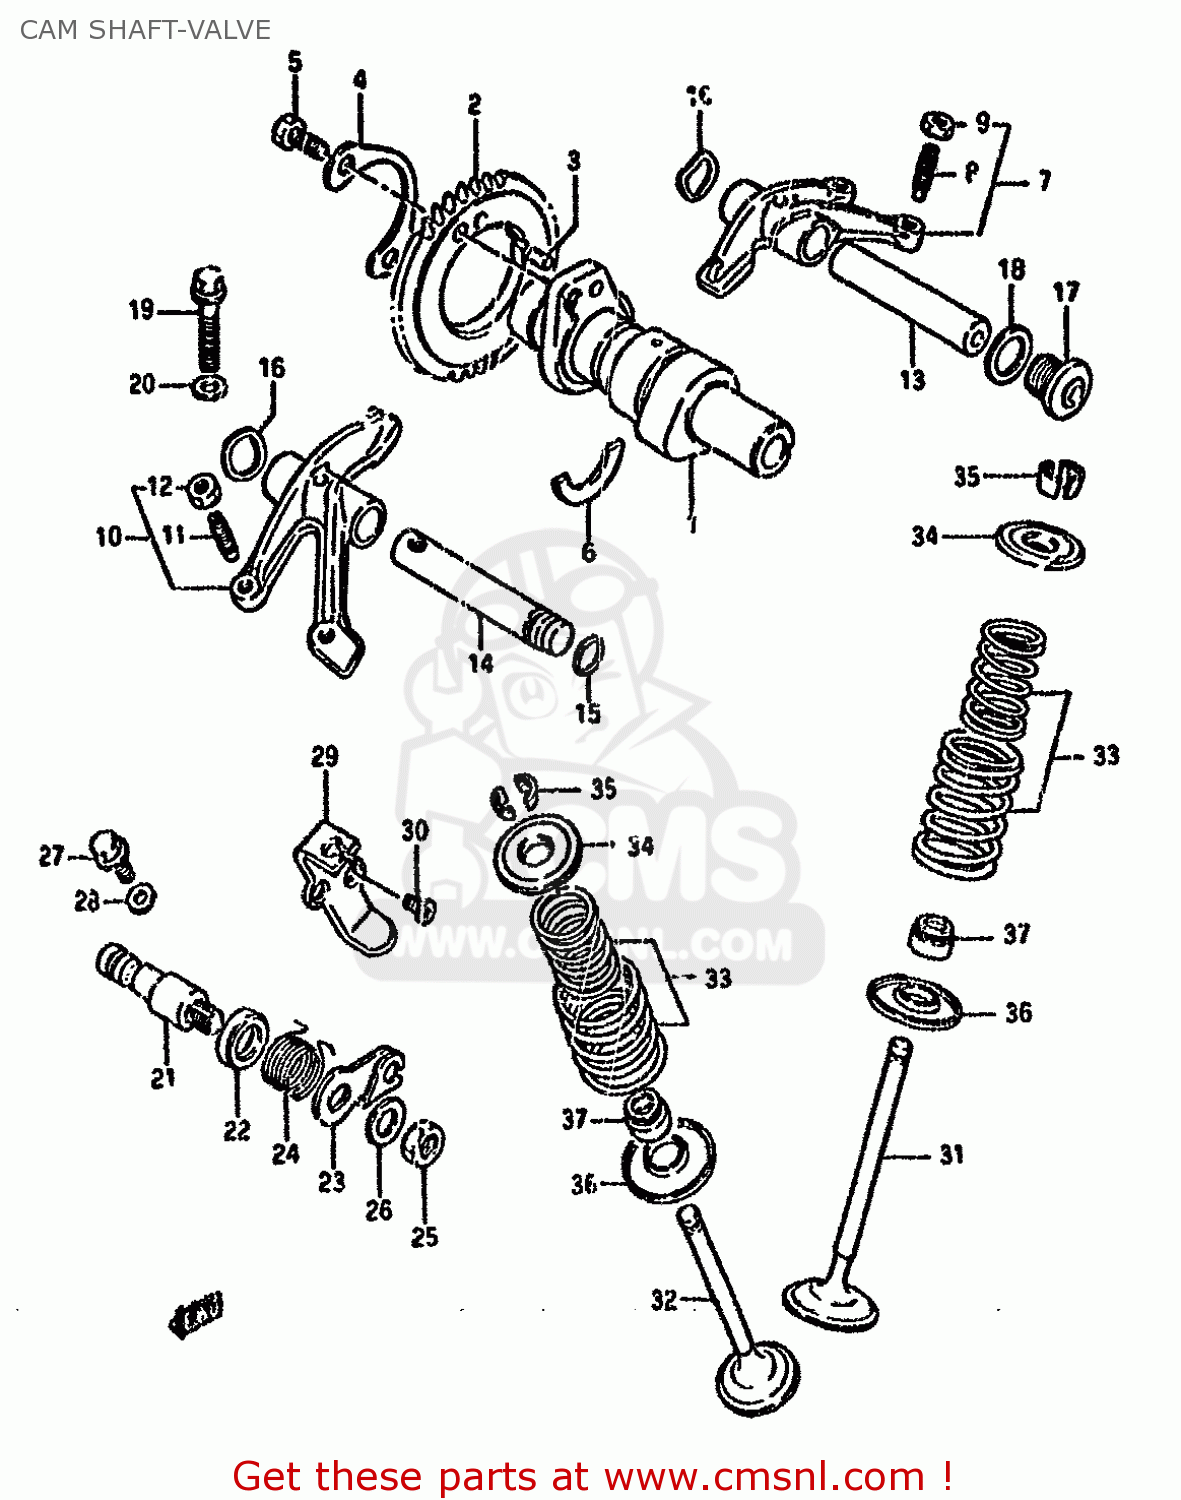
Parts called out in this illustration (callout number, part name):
1	CAMSHAFT
2	SPROCKET,CAMSHAFT
3	PIN(5X12.9)
4	WASHER,CAM CHAIN SPROCKET
5	BOLT(6X16)
6	C RING
7	ARM,VALVE ROCKER,INTAKE
8	SCREW,TAPPET ADJUSTING
9	NUT,ADJUSTING SCREW
10	ARM,VALVE ROCKER,EXHAUST
11	SCREW,TAPPET ADJUSTING
12	NUT,ADJUSTING SCREW
13	SHAFT,VALVE ROCKER ARM INTAKE
14	SHAFT,EXHAUST VALVE ROCKER ARM
15	O RING(D:1.9,ID:8.6)
16	WASHER
17	PLUG
18	GASKET(13.8X18.8X4.8) (NAS)
19	BOLT
20	GASKET(5.8X13X1.2) (NAS)
21	SHAFT,DECOMPRESSION,LEFT
22	SEAL,OIL(10X20X6)
23	LEVER,DECOMP SHAFT,L
24	SPRING
25	NUT
26	WASHER
27	BOLT(6X16)
28	GASKET(5.8X13X1.2) (NAS)
29	HOLDER,DECOMP CABLE,L
30	SCREW
31	VALVE,INTAKE
32	VALVE,EXHAUST
33	SPRING SET,VALVE
34	RETAINER,VALVE SPRING
35	COTTER,VALVE
36	SEAT,VALVE SPRING
37	SEAL,OIL(7X14.4X9)
